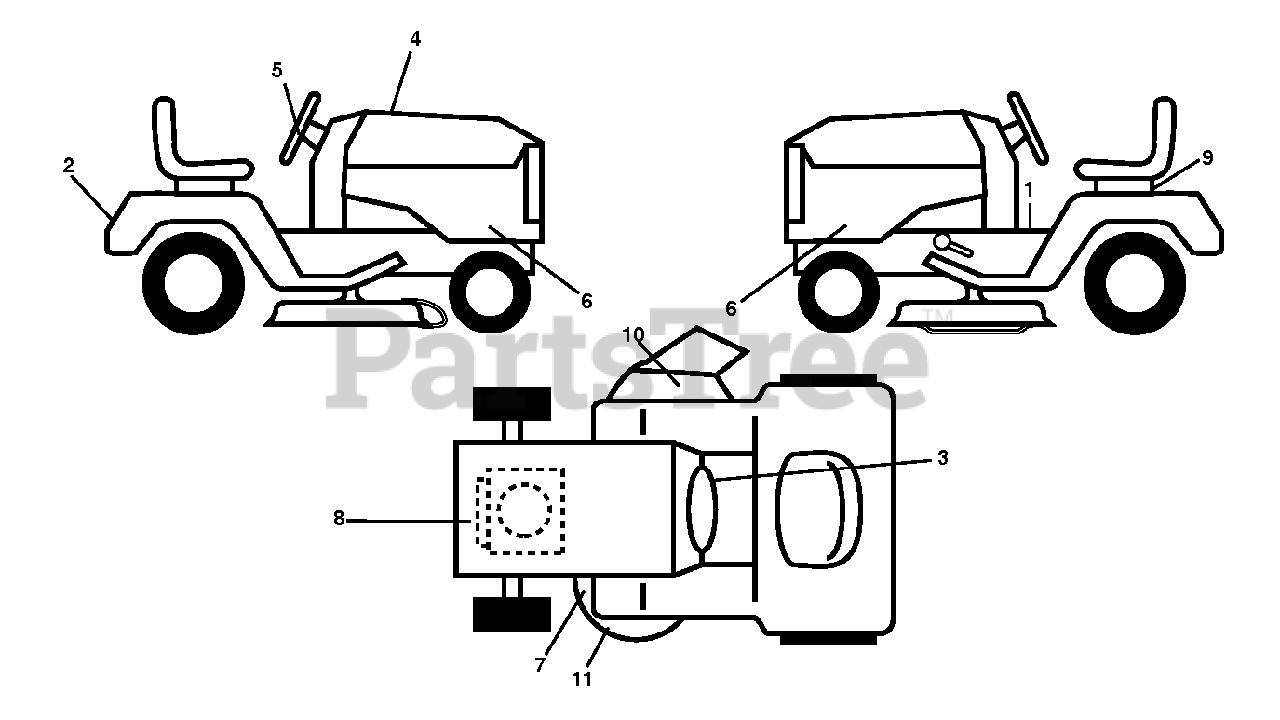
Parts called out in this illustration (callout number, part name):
1	DECAL.FENDER.WARNING.ENGLISH
2	DECAL.REARFNDR.POULAN PRO.2015
3	DECAL, WARNING SPARK ARRESTOR
4	DECAL DECAL.RPL.BSM33.INTK.LT.
5	Decal, Steering Wheel STDXXSQ PPRO 2015
6	Tractor Side Panel Decal
7	DECAL.PPRO.10YRDECKWAR.POP
8	Decal, Engine BS 19INTK DOM 381714
9	DECAL BTRY SYMBOLS
10	DECAL, DECK DEFLECTOR, WARNING
11	DECAL.V-BELT.SCH.42/46"MEC/ELE
